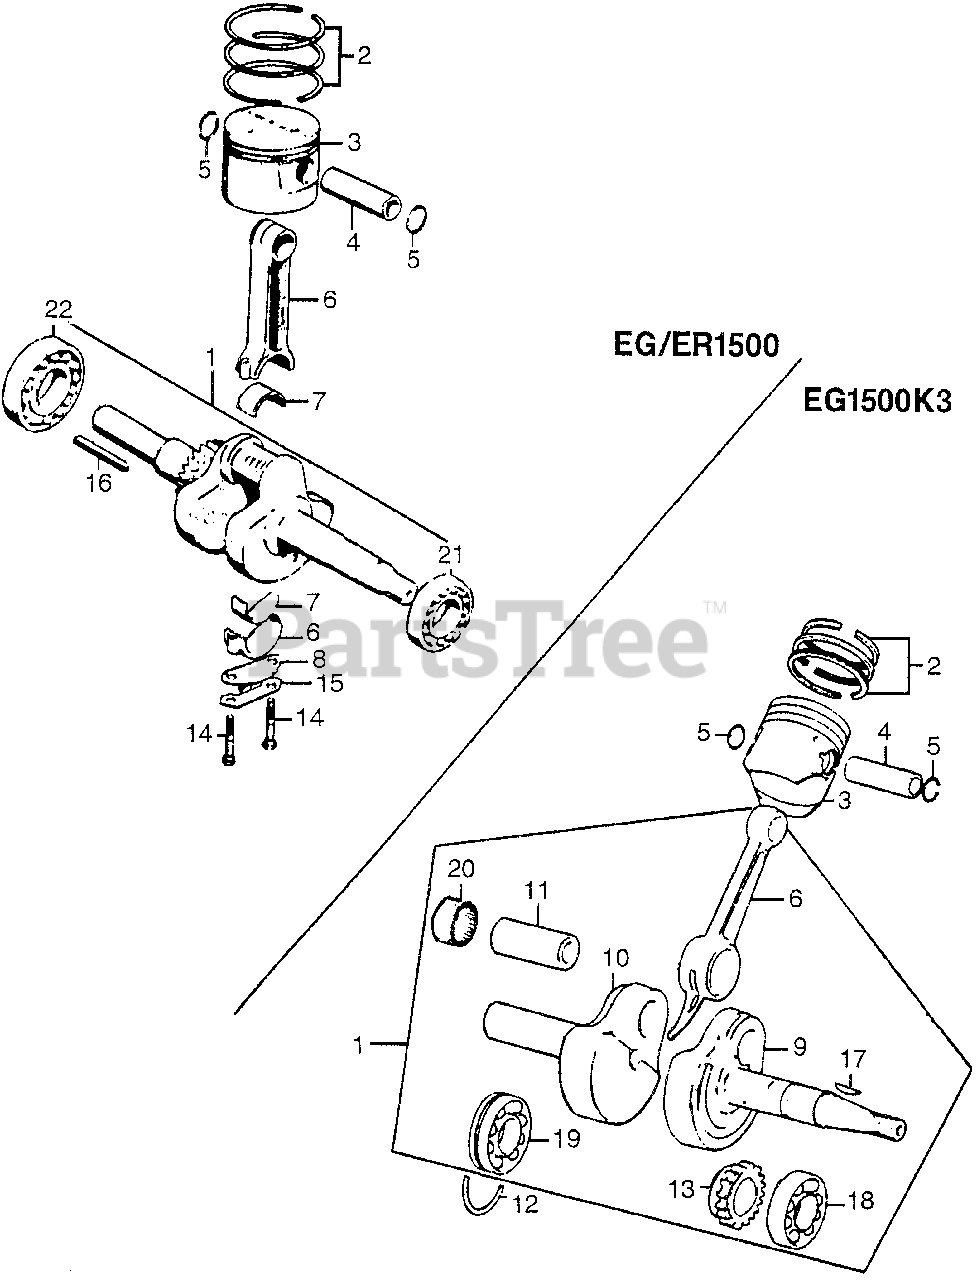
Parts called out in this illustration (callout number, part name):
1	CRANKSHAFT ASSY.
2	RING SET, PISTON (STD)
2	RING SET, PISTON (OS 0.25)
2	RING SET, PISTON (OS 0.50)
2	RING SET, PISTON (0.75)
3	PISTON (STD) (NOT AVAILABLE)
3	PISTON (OS 0.25)
3	PISTON (OS 0.50)
3	PISTON (0.75)
4	PIN, PISTON
5	CLIP, PISTON PIN (18MM)
6	ROD, CONNECTING
9	CRANKSHAFT, R.
10	CRANKSHAFT, L.
11	PIN, CRANKSHAFT
12	RING, BALL BEARING SET (NOT AVAILABLE)
13	GEAR, TIMING
17	KEY, WOODRUFF (NOT AVAILABLE)
18	BEARING, BALL (6304S) (NOT AVAILABLE)
19	BEARING, RADIAL BALL (6206SHS) (NOT AVAILABLE)
20	ROLLER, ROD (2.48X18.8)
